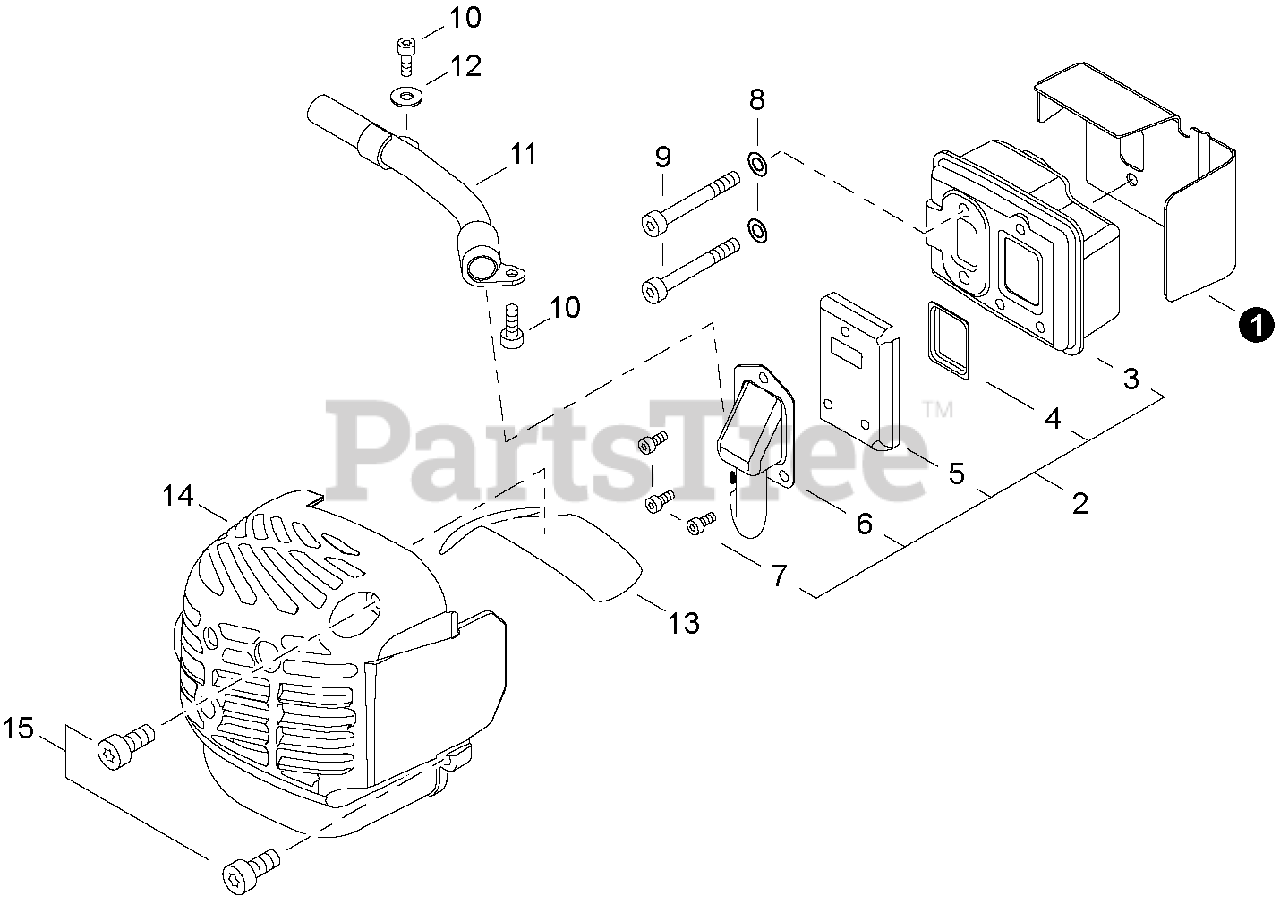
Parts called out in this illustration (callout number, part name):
1	HEAT SHIELD, EXHAUST
2	MUFFLER ASSY
3	MUFFLER
4	SCREEN, SPARK ARRESTER
5	GASKET, EXHAUST
6	GUIDE, EXHAUST
7	BOLT, TORX 4×8
8	WASHER 5.5×12×0.8
9	BOLT, TORX 5×55
10	BOLT, TORX 5×10
11	GUIDE, EXHAUST
12	WASHER 5
13	PLATE, INSULATOR
14	COVER, MUFFLER
15	BOLT, TORX 5×16
